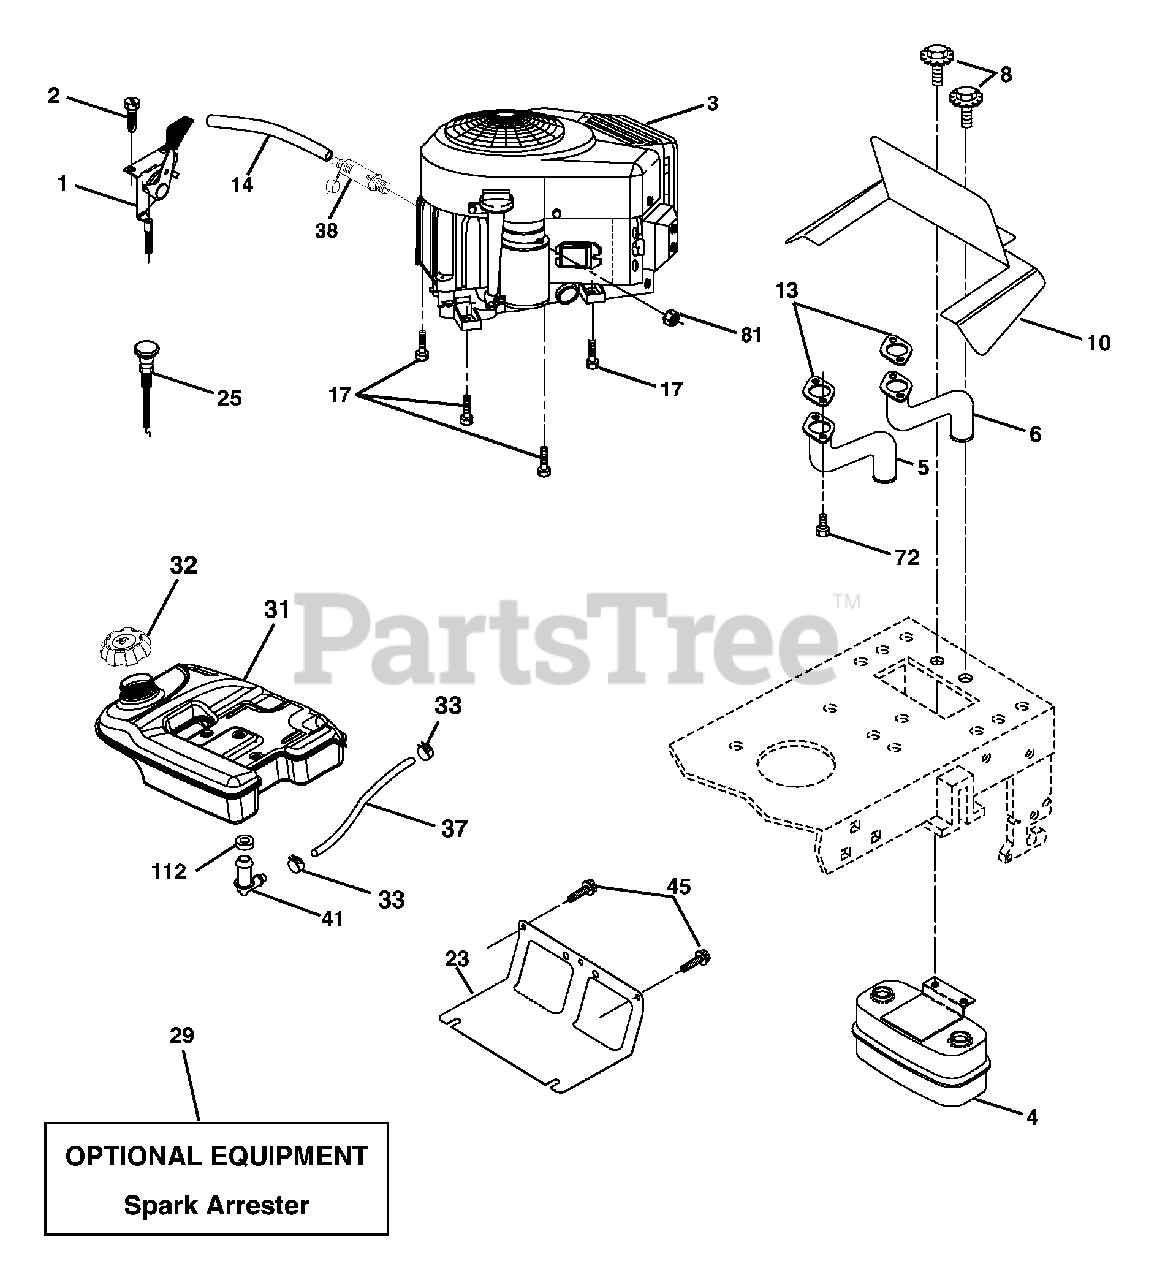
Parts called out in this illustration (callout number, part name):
1	Control, Throttle/Choke
2	Screw Hex Single Lead 10 x 3/4
4	Muffler
5	Tube Exhaust LH
6	Tube Exhaust RH
8	Bolt 5/16-18 unc x 3/4 w/Sems
10	Shield Browning
13	Muffler Gasket
14	Tube Oil Drain
17	Screw 3/8-16 x 1-1/2
23	Shield, Browning/Debris Guard
29	Arrester, Spark
31	Tank, Fuel
32	Cap Gauge, Fuel
33	Clamp, Hose Blk
37	Line, Fuel
38	Plug Drain Oil Easy
41	Stem Tank Fuel
45	Screw Hex Wsh Thdrol 3/8-16 x 3/4
72	Screw 5/16-18 x 1
81	Nut Keps Hex 1/4-20 unc
112	Bushing
